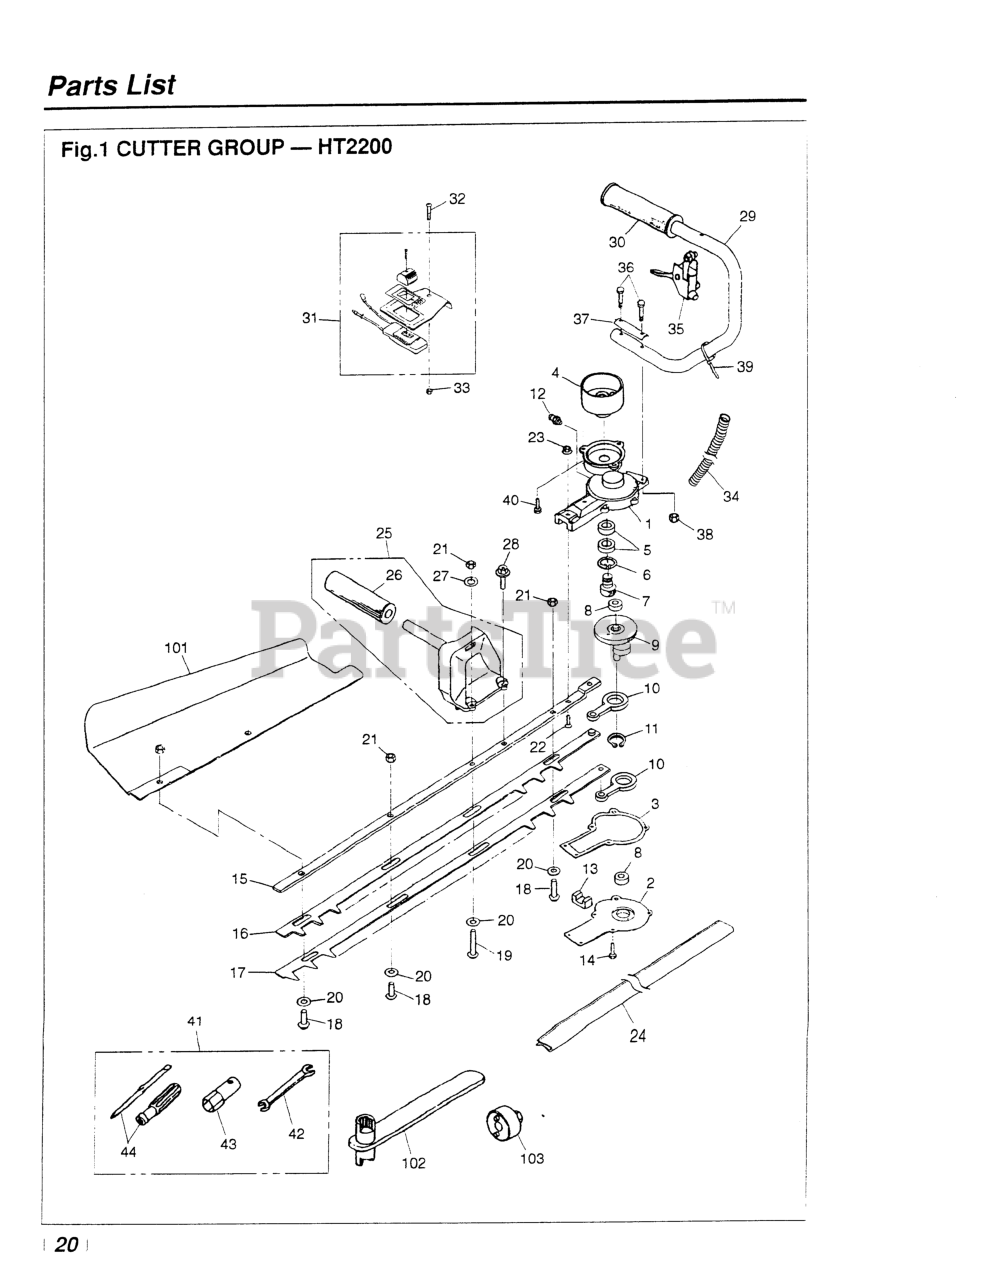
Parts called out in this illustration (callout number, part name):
1	GEARCASE
2	COVER
3	GASKET
4	DRUM, CLUTCH
5	BEARING
6	RING, SNAP
7	PINION
9	GEAR COMPL
10	ROD
11	RING, SNAP, M25 X 1.2
12	FITTING, GREASE
13	FELT
14	BOLT
15	PLATE, GUIDE
16	BLADE, UPPER
17	BLADE, LOWER
20	WASHER (RPLS 3873-11760)
21	NUT, M6
22	SCREW
23	NUT
24	COVER, BLADE
25	HANDLE COMPL
26	GRIP (RPLS -13120)
28	BOLT
29	HANDLE COMP.
30	GRIP (RPLS -13120)
31	SWITCH
33	NUT, M5 X 4
34	TUBE
35	LEVER ASSEMBLY
36	BOLT, M5x25 (RPLS -50520)
38	NUT (RPLS 3873-14470)
39	BAND, CABLE
40	BOLT, M6 X 14
41	TOOL SET
42	SPANNER, 8 X 10 (RPLS 2540- )
43	SOCKET, HEX, 3/4
44	SCREWDRIVER
101	RECEIVE PLATE
103	WRENCH (TOOL)
